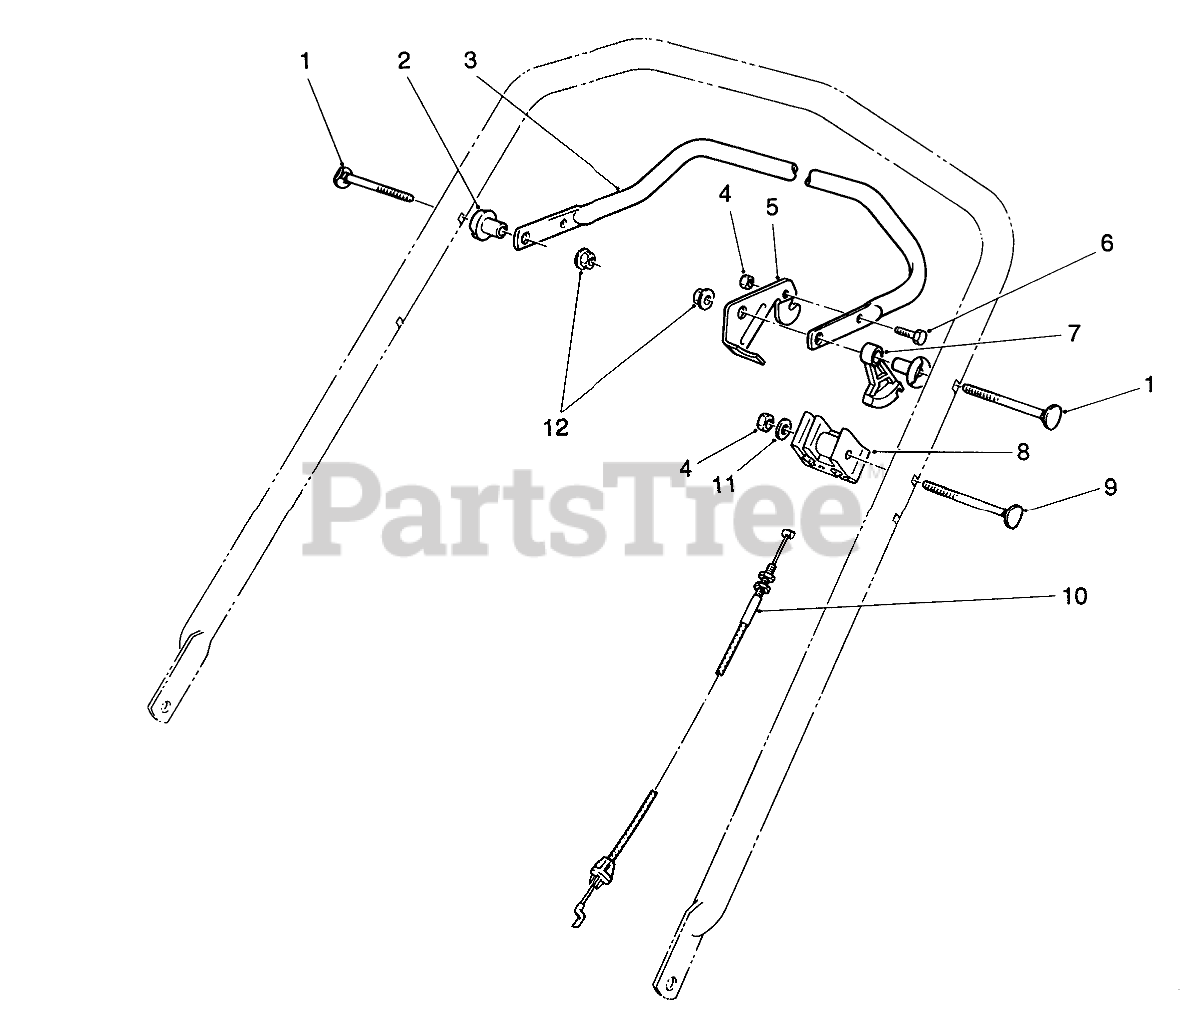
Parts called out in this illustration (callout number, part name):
1	SCREW-HANDLE
2	SPACER-SUPPORT
3	Bar-Control
4	NUT-LOCK, NI
5	CONTROL LEVER
6	SCREW-HH
7	LEVER-TRACTION
8	SUPPORT-CABLE
9	SCREW-HANDLE
10	TRACTION CABLE
11	WASHER-FLAT
12	NUT-LOCK, NI
